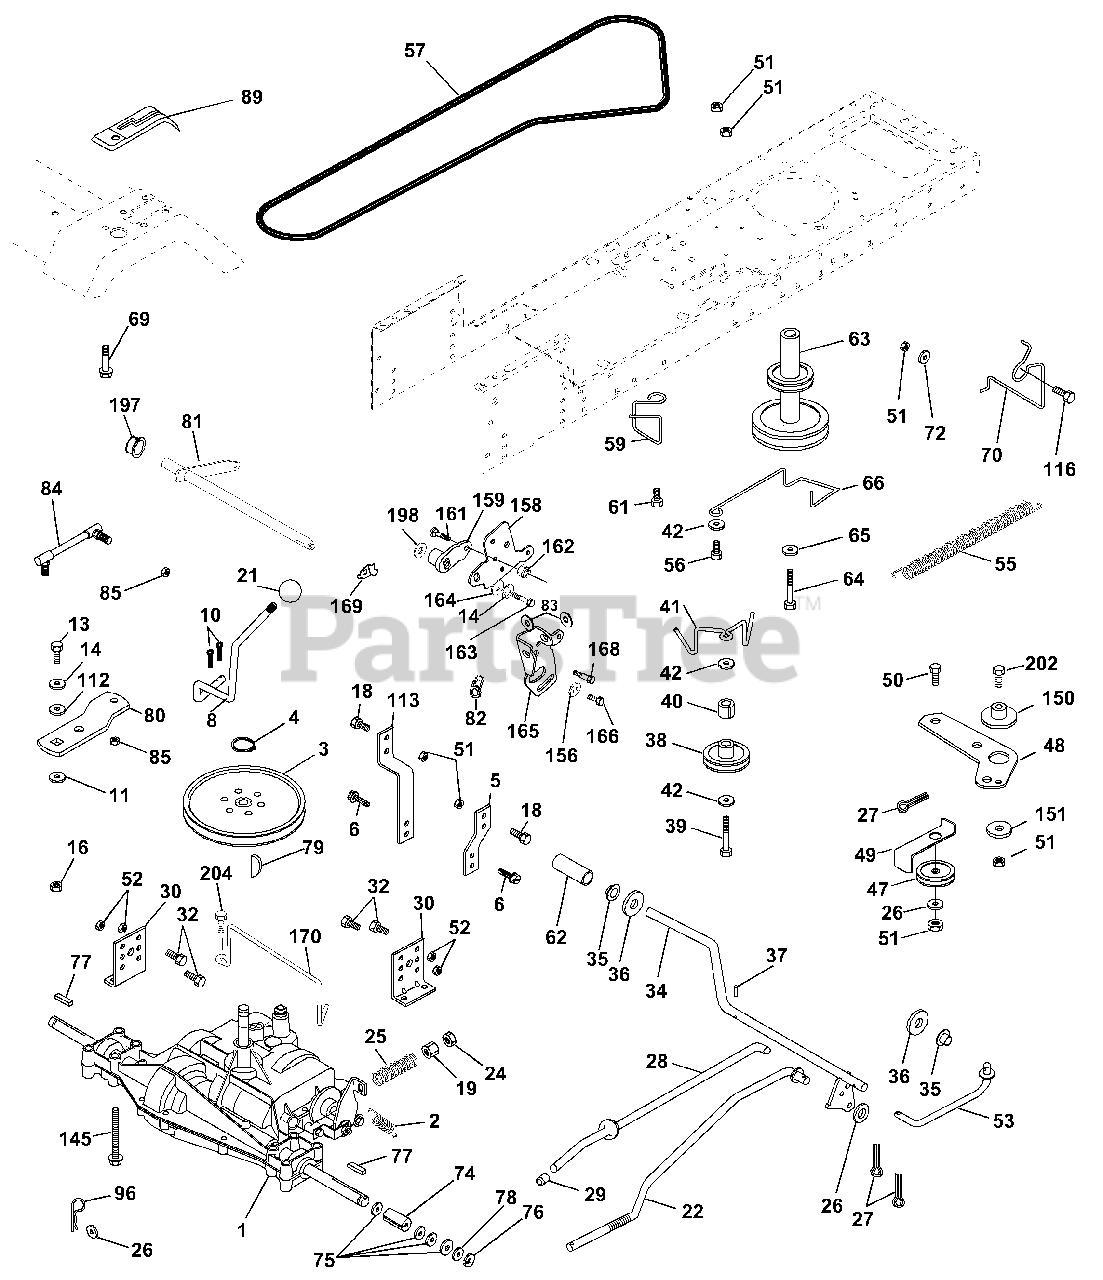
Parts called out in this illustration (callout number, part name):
2	Spring Return Brake T/a Zinc
3	Pulley Transaxle 18" tires
4	Ring Retainer #5100-62
5	Strap Torque 30 Degrees
6	Screw 5/16-18 X 3/4
8	Rod Shift Fender Adjust Lt
10	Pin Cotter 1/8 X 1 Cad
11	Washer Plate Shf 388 Sq Hole
13	Bolt 1/4-28 Unf Gr 8 W/Patch
14	Washer Lock Hvy Helical
16	Nut Lock Hex w/Ins 5/16-18 Unc
18	Bolt, Fin Hex 3/8-16 UNC x 1 Gr. 5
19	Nut Lock 3/8-16 Unc
21	Knob
22	Rod Brake Blk Zinc 26 840
24	Nut Hex Jam 3/8-16 Unc
25	Spring Rod Brake 2 00 Zinc
26	Washer 13/32 X 13/16 X 16 Ga
27	Pin Cotter 1/8 X 3/4 Cad
28	Rod Brake Parking LT/YT
29	Cap Brake Parking
30	Bracket Mtg Transaxle
32	Bolt Hex Hd 5/16-18unc X 3/4
34	Shaft Asm Pedal Foot
35	Bearing Nylon Blk 629 Id
36	Washer 21/32 X 1 X 16 Ga
37	Pin Roll 3/16 X 1"
38	Pulley Idler Flat
39	Bolt Rdhd 3/8-16 unc X 2-3/4 Gr. 5
40	Spacer Split 395 X 59 Bzp
41	Keeper Belt Flat Idler
42	Washer 13/32 X 13/16 X 12 Ga
47	Pulley Idler V Groove Plastic
48	Bellcrank Asm
49	Retainer Belt Style Spring
50	Bolt Hex Hd 3/8-16unc X 1-1/2
51	Nut Crownlock 3/8-16 Unc
52	Nut Crownlock 5/16-18 Unc
53	Link Clutch
55	Spring Return Clutch 6 75
56	Bolt Fin Hx 3/8-16 X 1/4
57	V-Belt Ground Drive 95 25
58	Keeper Belt RH LT Pnt/zinc 16g
59	Keeper Belt Span Ctr
61	Screw 3/8-16 x .75
62	Cover Pedal Blk Round
63	Engine Pulley LT/YT
64	Bolt Hex
65	Washer Lock Hvy Hlcl Spr 7/16
66	Keeper Belt Engine Foolproof
69	Screw Hex Wsh Hi-Lo 1/4-1/2 Unc
70	Guide Belt Mower Drive RH
72	Washer 13/32 X 1-1/4 X 12 Ga
74	Spacer Axle
75	Washer 25/32 X 1 1/4 X 16 Ga
76	E-ring#5133-75
77	Key Square 2 0 X 1845/ 1865
78	Washer 25/32 X 1-5/8 X 16 Ga
79	Key Woodruff #9 3/16 x 3/4
80	Arm Shift
81	Shaft Asm Cross Tapered PMST/20
82	Spring Torsion T/a
83	Washer 17/32 X 3/4 X 16 Ga
84	Link Transaxle PMST/20" Zinc
85	Nut Lock Center 1/4 - 28 FNTHD
89	Console Shift STLT
96	Retainer Spring 1"
112	Washer 9/32 x 3/4 x 10 Ga.
113	Strap Torque LT
116	Bolt Rdhd Sq Neck 3/8-16 x 1.25
145	Bolt Hex FLGHD 5/16-18 Gr. 5
150	Bushing Bellcrank
151	Washer 13/32 x 2 x 10
156	Washer Srrted 5/16 ID x 1.125
158	Bracket Shift Mount
159	Hub Tapered Flange Shift Lt
161	Bolt Rdhd Sqnk 1/4-20 x 3/4 Gr
162	Nut Crownlock 1/4-20 Unc
163	Bolt Hex Fin 1/4-20 Unc x 1 Gr 5
164	Washer 5/8 x .281 x 10 Ga
165	Bracket Pivot Lever
166	Screw 5/16-18 x 5/8
168	Bolt Shoulder 5/16-18 x .561
169	Plate Fastening
170	Keeper Belt Transaxle Gear
197	Nyliner Snap-In
198	Washer Nyliner
202	Bolt Carr Sh 3/8-16 x 1-1/2 Gr. 5
204	Screw 5/16-18 x 1
